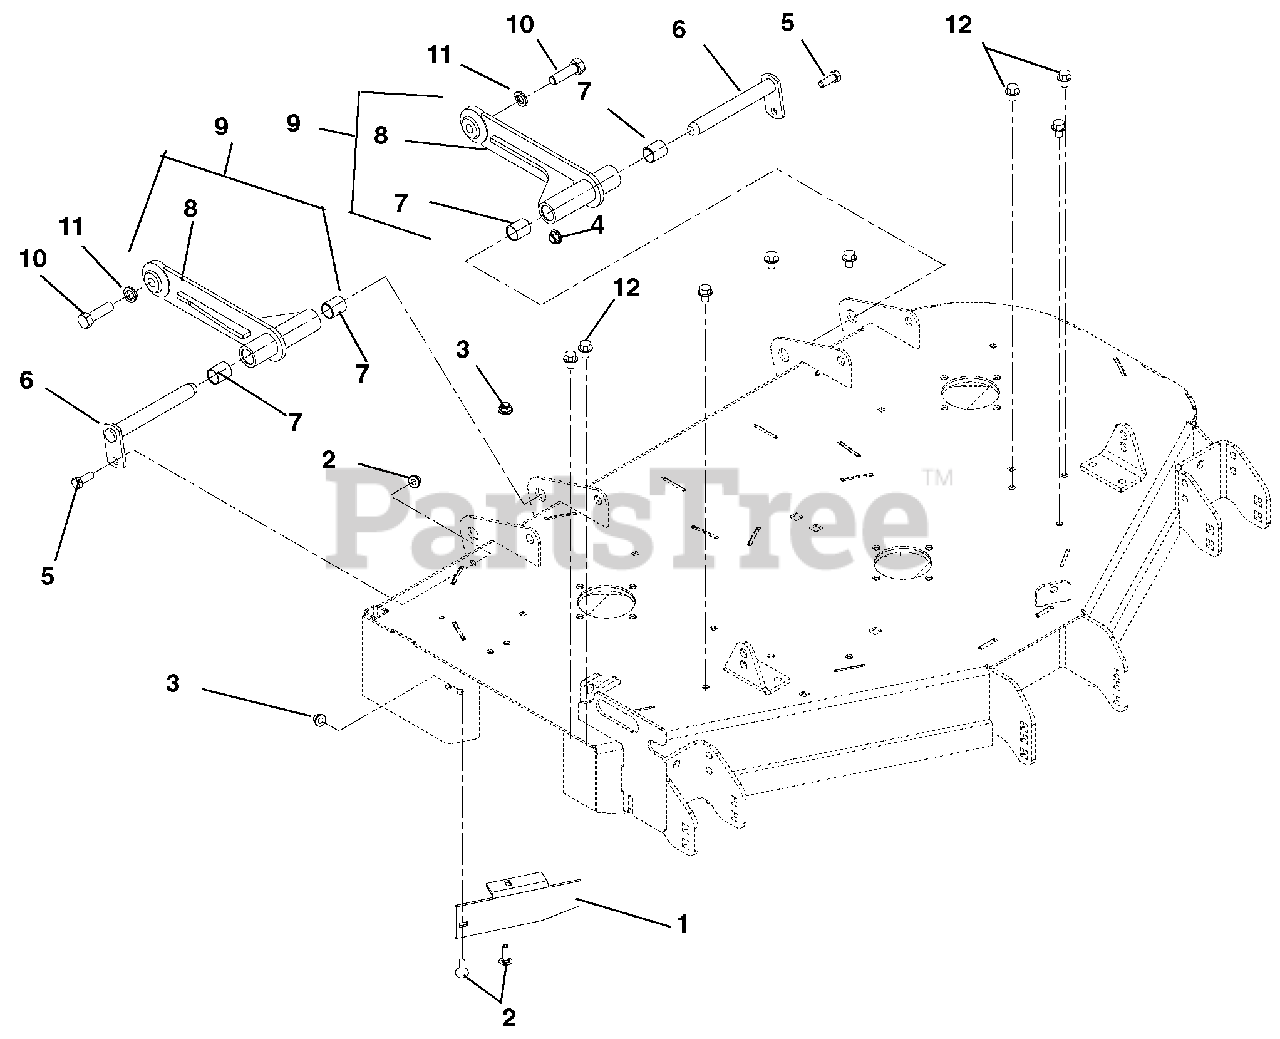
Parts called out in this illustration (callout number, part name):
1	44" - 48" Rear Discharge Baffle
2	Bolt, Round Head Square Neck .31-18 x 1.00 Grade 5
3	Nut, .31-18 Nyloc Flange
4	Nut, .38-16 Nyloc Flange
5	Bolt-Hex .38-16X1.00 Grade 5
6	Weldment, Mower Mounting Pin
7	Bearing, .75 x .875 x 1.00
8	Deck Pusher Arm Weldment
9	Assembly, Mower Mount Arm
10	Bolt, Hex .50-13 x 1.75 Grade 5
11	Washer, Locking .50 x .125 Regular
12	Screw, Tapping .38-16 x .50 Hex Washer Head
